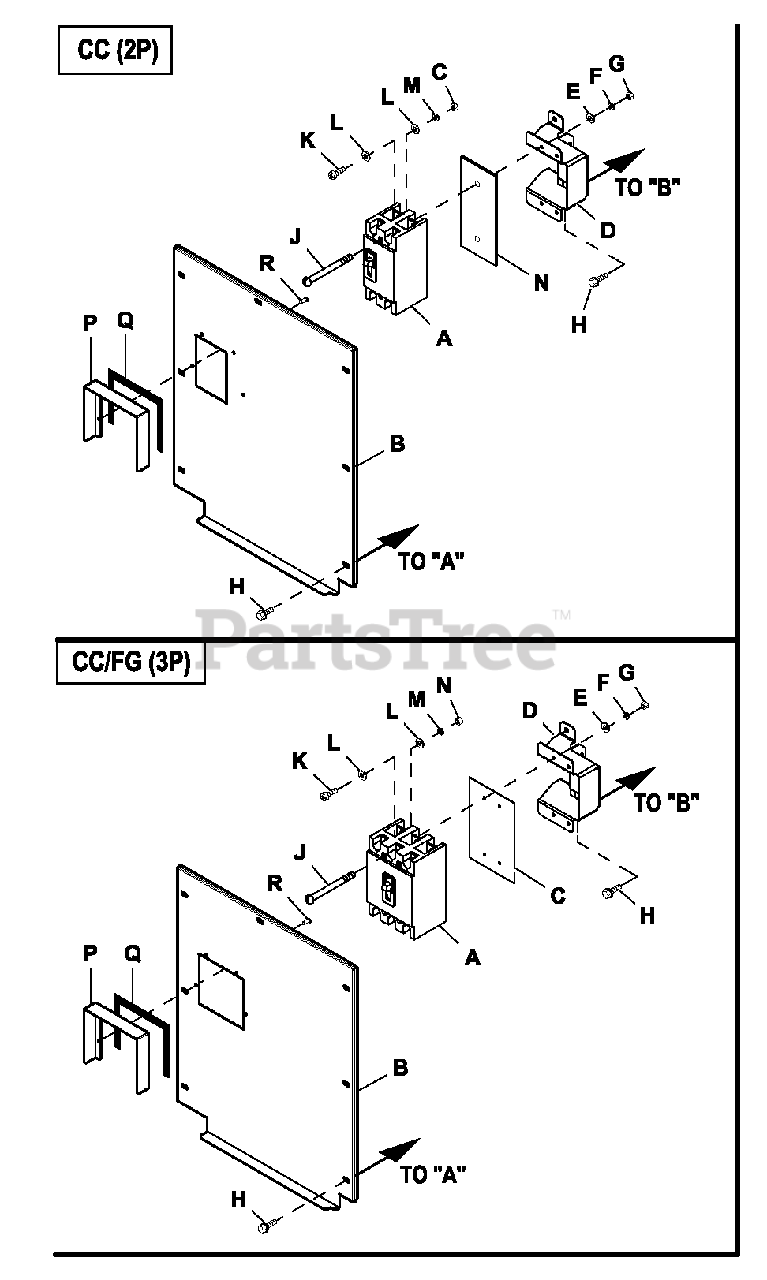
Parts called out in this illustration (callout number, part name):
A	CB0100A2P 2 4 0V EC C LL
B	COVER CB E CC 2P C1 CONBOX
C	NUT HEX M5-0.8 G8 CLEAR ZINC
D	CIRCUIT BREAKER SUPPORT (CC)
E	WASHER FLAT #8 ZINC
F	WASHER LOCK #8-M4
G	NUT HEX #8-32 STEEL
H	SCREW HWHT M6-1 X 16 N WA Z/JS
J	SCREW RHM #8-3 2X3 -1 /4
K	SCREW PPHM M5-0.8 X 12 ZNC
L	WASHER FLAT #10 ZINC
M	WASHER LOCK M5
N	INSULATOR CB 2P E TYPE CC
P	SHIELD CB HANDLE CONBOX
Q	TAPE ELEC 1/2 FOAM
R	RIVET POP .125 X .275 SS
A	CB 0100 3P 240V E CC LL
B	CB COVER E CC/FG 3P C1 CONBOX
C	INSULATOR CB 3P E TYPE CC/FG
F	WASHER LOCK#8-M4
J	SCREW PPHM #8-32 X 1-3/4 ZINC (CC)
N	NUT HEX M5-0.8 G8 CLEAR ZINC
